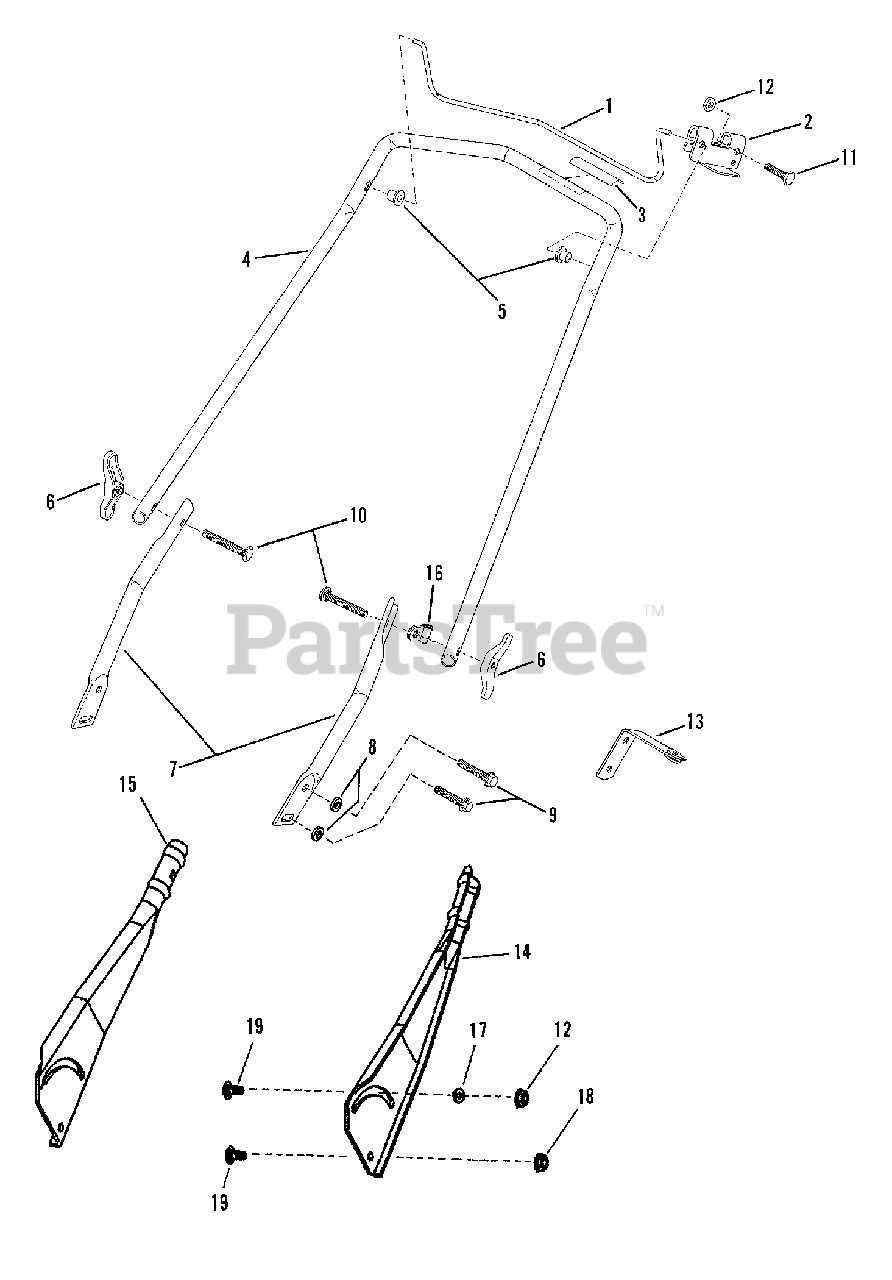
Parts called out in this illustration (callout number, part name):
1	CONTROL, Auger
2	CLIP
2	CLIP, 9
3	DECAL, Auger Control
4	HANDLE, Upper (white)
4	HANDLE, Upper (black)
5	BUSHING
6	T-KNOB (Plastic)
7	HANDLE, Lower
8	WASHER, 1/4 Flat
9	SCREW, 1/4-20 x 1-3/8" Hex Washer Self-Tap
10	BOLT, 1/4-20 x 2" Short Square Neck Carriage, Grade 5
11	SCREW, 1/4-20 x 1/2" Hex Head cap, Grade 5
12	NUT, 1/4-20 Hex Center Lock, Grade B or 5
13	ASSEMBLY, Bracket & Bushing
14	HANDLE, Lower, L.H.
15	HANDLE, Lower R.H.
16	CLAMP, Cable
17	RETAINER, 1/4" Bolt
18	NUT, 1/4-20 Hex Flange Lock
19	BOLT, 1/4-20 x 1-3/8" Square Neck Carriage, Grade 5
